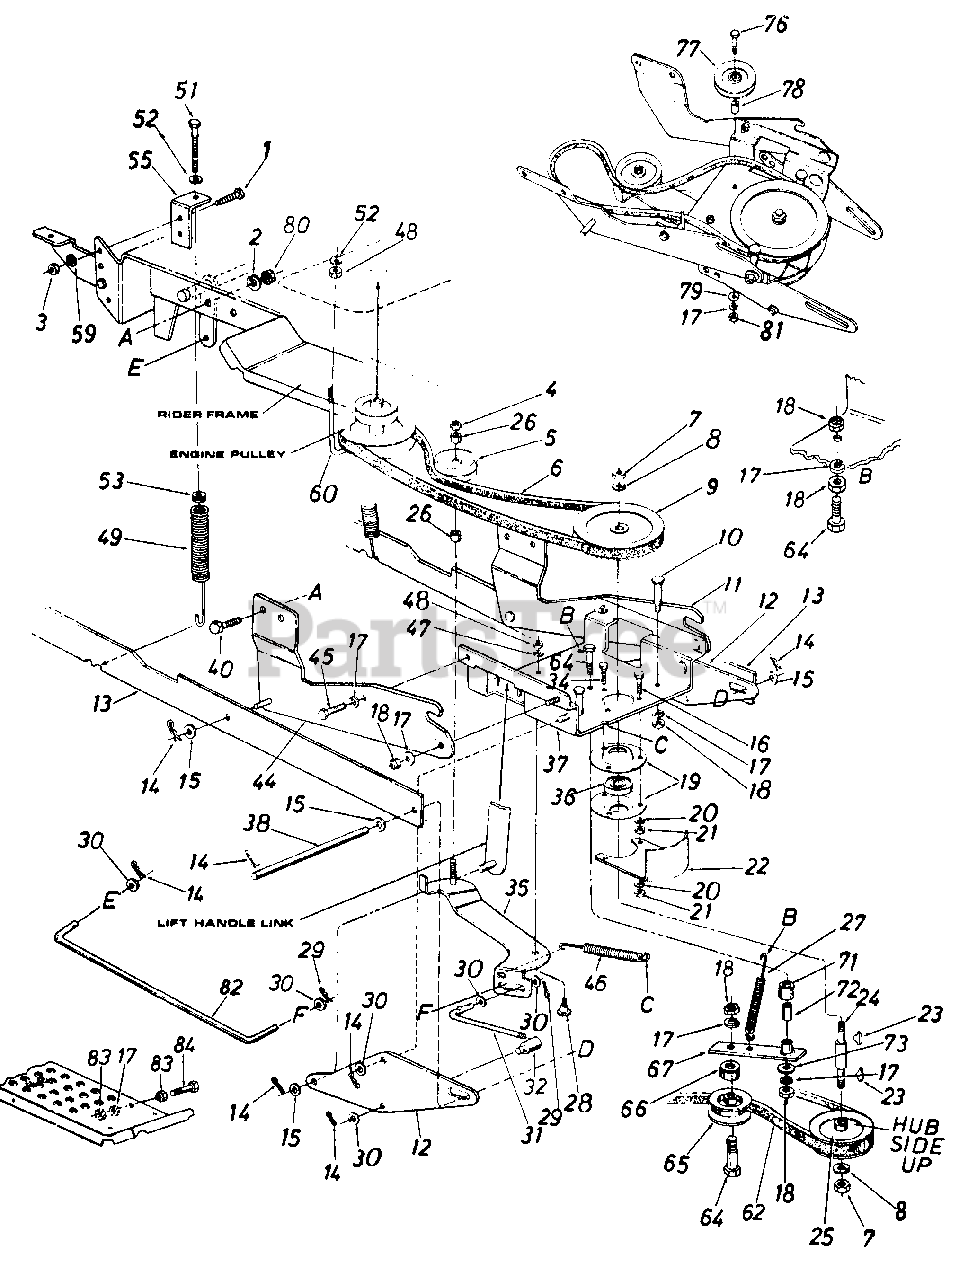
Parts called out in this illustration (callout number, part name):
1	Hex Bolt 1/4-28 x 1.00" Lg. Grade 5
2	L.-Wash. 1/4" I.D.*
3	Hex Nut 1/4-28 Thd.*
4	Hex Cent. L-Nut 3/8-16 Thd.
5	Idler Pulley
6	"V"Belt
7	Hex Jam Nut 5/8-11 Thd.
8	L.-Wash. 58" I.D.*
9	6.50" O.D. x 5/8 Pulley
10	Shoulder Bolt
11	Channel Support Brkt.-R.H.
12	Linkage Brkt.
13	Linkage Arm Ass'y.
14	Intern. Cotter Pin .50 Dia.*
15	Fl.-Wash.
16	Hex Bolt 5/16 x 1.25" Lg.
17	L.-Wash. 3/8" I.D.*
18	Hex Jam Nut 3/8-16 Thd.
19	Bearing Housirlg
20	L.-Wash. 5/16" I.D.*
21	Hex Nut 5/16-18 Thd.*
24	Pulley Spindle
25	5/8 Pulley-6.28 I.D. x 5.56 0. D.
26	Spacer .383 I.D. x .503 O.D. x .562 Lg.
27	Extension Spring .54 O.D. x 5.25"
28	Shoulder Bolt
29	Cotter Pin 3/32" Dia.
30	Fl.-Wash.
31	Control Rod
32	Ferrule
34	Hex Sems Scr. 5/16-18 x .75" Lg.*
35	Clutch Idler Brkt. Ass'y.
36	Ball Bearing
37	Channel Ass'y.
38	Lift Handle Shaft
40	Hex Self-Tap Scr. 1/4-20 x .75" Lg.
44	Channel Supporting Brkt. -L.H.
45	Hex Bolt 3/8-16 x 1.0 Lg.
46	Extensioll spring
47	L. Wash. 5116 I.D.
48	Hex Nut 5i16-18 Thd.
49	Helper Spring
51	Hex Ser. 5/16-18 x 2.0" Lg. Special
52	Bell Wash. .345 I.D. x .88 O.D. x .06
53	Spring Insert
60	J.-Bolt 5/16-18 Thd.
62	V eelt 1/2 "A" x .89" Lg.
64	Hex Bolt 3/8-16 x 2.0" Lg.
65	Idler Pulley
66	Spacer .385 I.D. x .503 O.D. x .562 Lg.
67	Idler Arm Assy.
71	Spacer .380 I.D.
72	Spacer .3775 I.D. x .60 O.D. x 8.3 Lg.
73	Fl.-Wash. 3/8 I.D. x 1 O.D.' x 1.27
76	Hex Bolt 3/8-16 x 2.5" Lg. (Grade 5)
77	Idler Pulley .38 I.D. x 3.06 1 O.D.
78	Spacer.385 I.D. x .630 O.D x .76 Lg.
79	Fl.-Wash. .39 I.D. x 1 3/4 O.D. x 3/16
80	Hex L-Nut 1/4-20 Thd.
81	Hex Nut 3/P.-16 Thd.*
82	Clutch Control Rod
83	Hex Nut 3/8-24 Thd.*
84	Hex Bolt 3/8-24 x 2.25" Lg.
